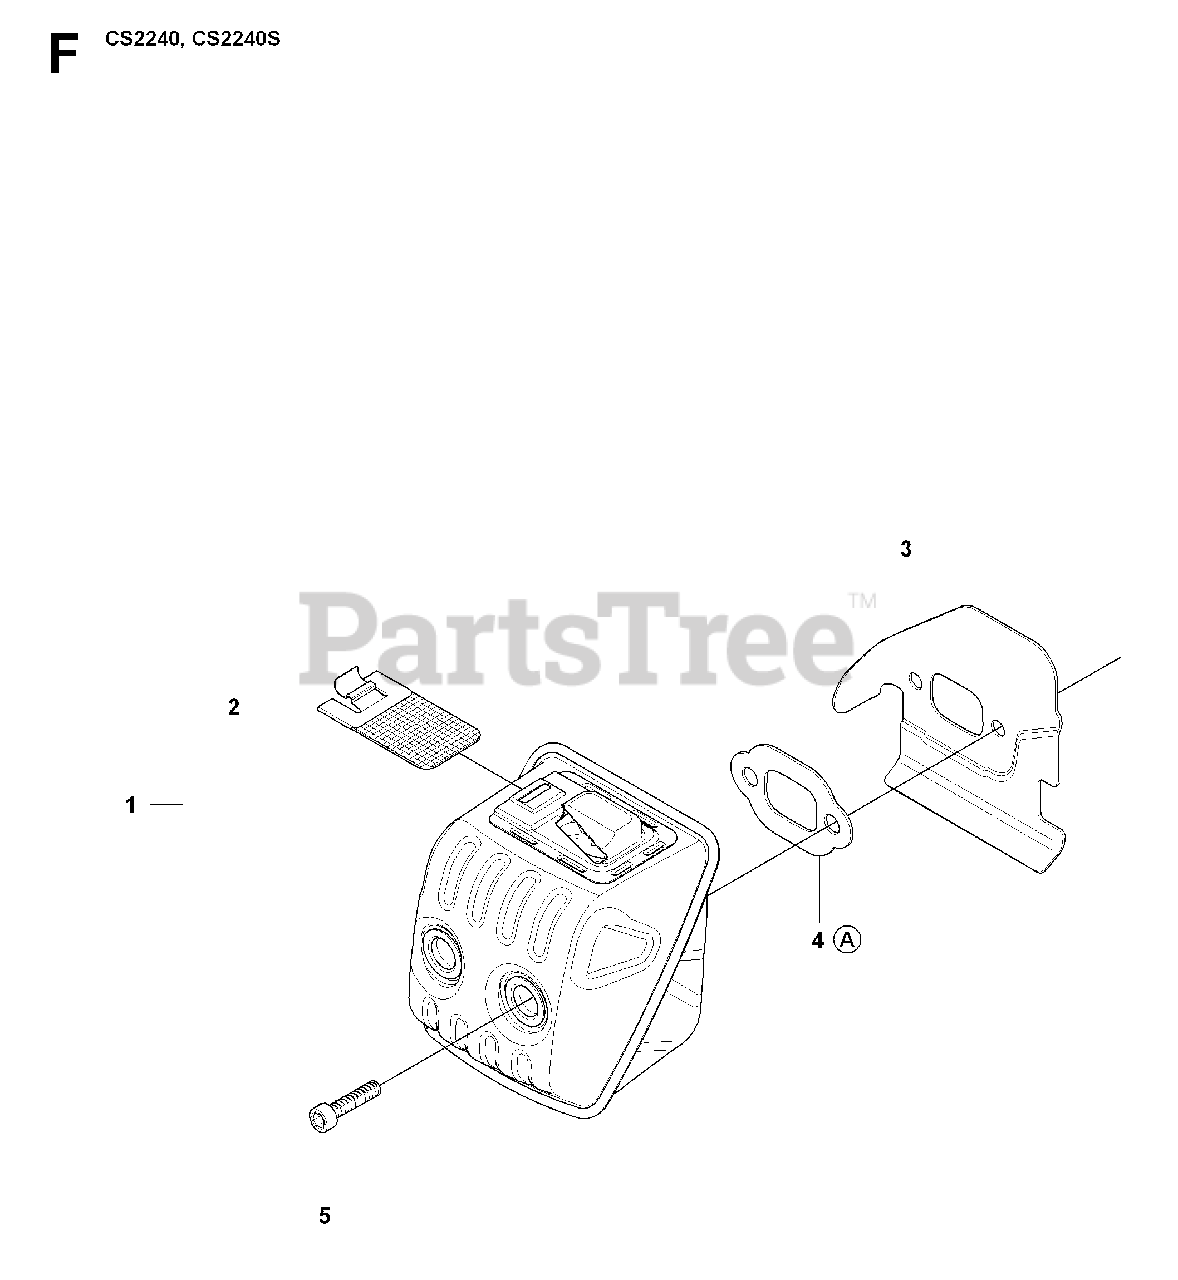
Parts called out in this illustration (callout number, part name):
1	%MUFFLER ASSY
2	SPARK ARRESTER
3	HEAT DEFLECTOR
5	SCREW MC6S 6X16
